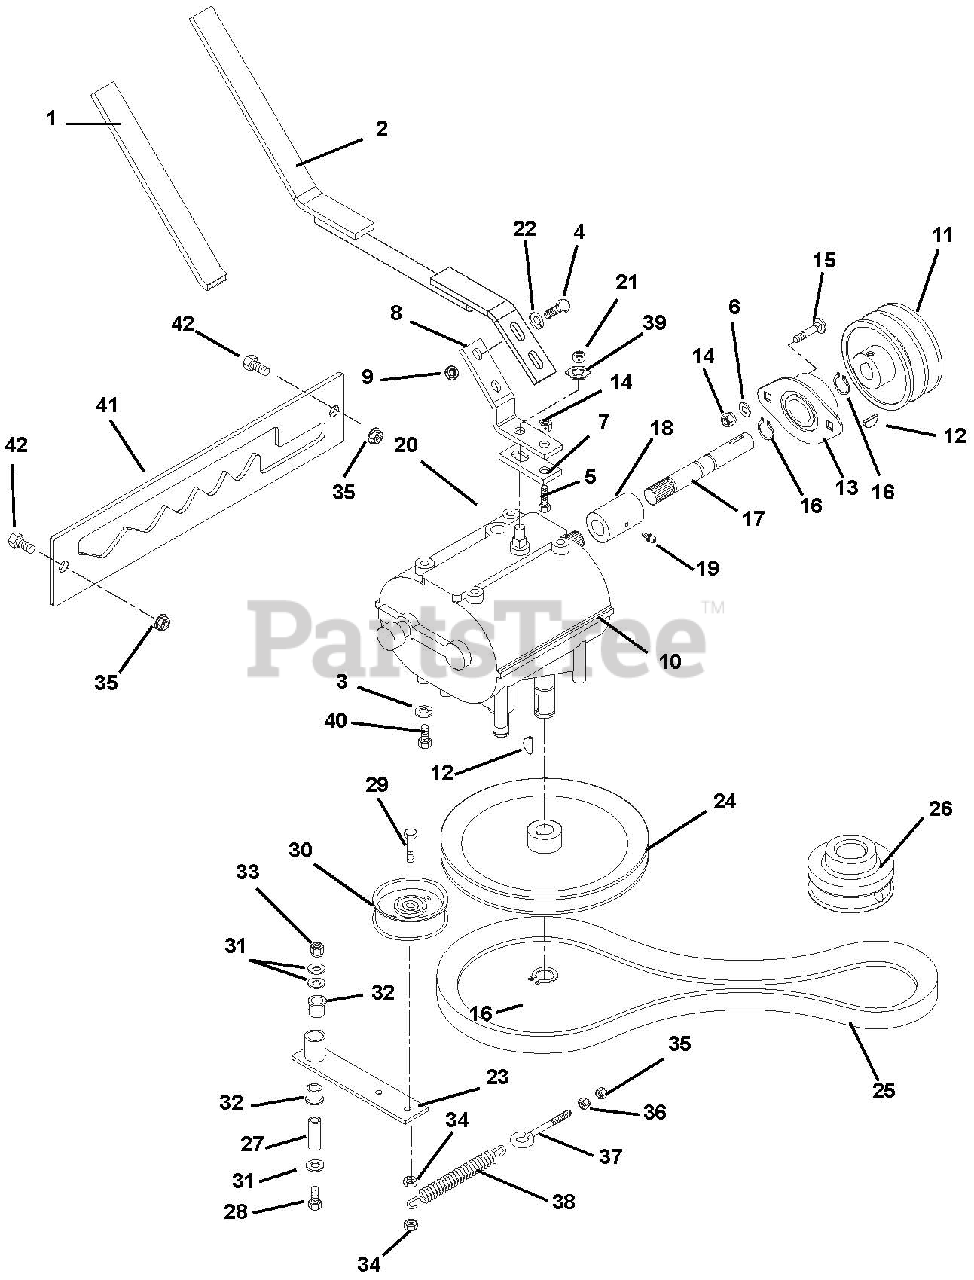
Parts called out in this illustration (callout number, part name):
1	Grip
2	Lever, Shift
3	Washer-Locking .31 x .078 Regular
4	Bolt-Hex .31-18 x 1.00 Grade 5
5	Bolt-Hex .25-20 x 1.00 Grade 5
6	Washer-Flat-Steel .25 x .562 x .049
7	Plate, Shift
8	Arm, Shift
9	Nut-Locking-Top-Flange .31-18
10	Transmission
11	Sheave, Drive
12	Key-Woodruff .19 x .75
13	Bearing-Flange .625 x 1.875 x .797
14	Nut-Locking-Nylon .25-20
15	Bolt-Round Head Square Neck .25-20 x .75 Grade 5
16	Ring-Retaining-External .579 x .930
17	Shaft, Half
19	Fitting, Lube, .25-28
20	Switch-Neutral Start
21	Nut-Locking-Center .38-24
22	Washer-Flat-Steel .344 x .688 x .065
23	Weldment, Ground Drive Idler
24	Pulley-V 7.50 x .63 Sheave Transmission
25	V-Belt 4L-Section 33.9
26	Sheave, Clutch
27	Bushing, Steel .56 x .745 x 2.04
28	Bolt-Hex .50-13 x 3.25 Grade 5
29	Bolt-Hex .38-16 x 2.00 Grade 5
30	Idler-Pulley Flat 3.25 x .625
31	Washer-Flat-Steel .531 x 1.06 x .095
32	Bushing-Flange Nylon .762 x 1.00 x .58 x 1.48
33	Nut-Locking-Nylon .50-13
34	Nut-Locking-Jam-Center .375-16
35	Nut-Locking-Nylon .38-16
36	Nut-Hex .38-16
37	Eye Bolt
38	Spring, Extension
39	Washer, Locking .38 x .13
40	Bolt-Hex .31-18 x .75 Grade 5
41	Plate, Shift Lever Detent
42	Bolt-Hex .38-10 x 1.00 Grade 5
